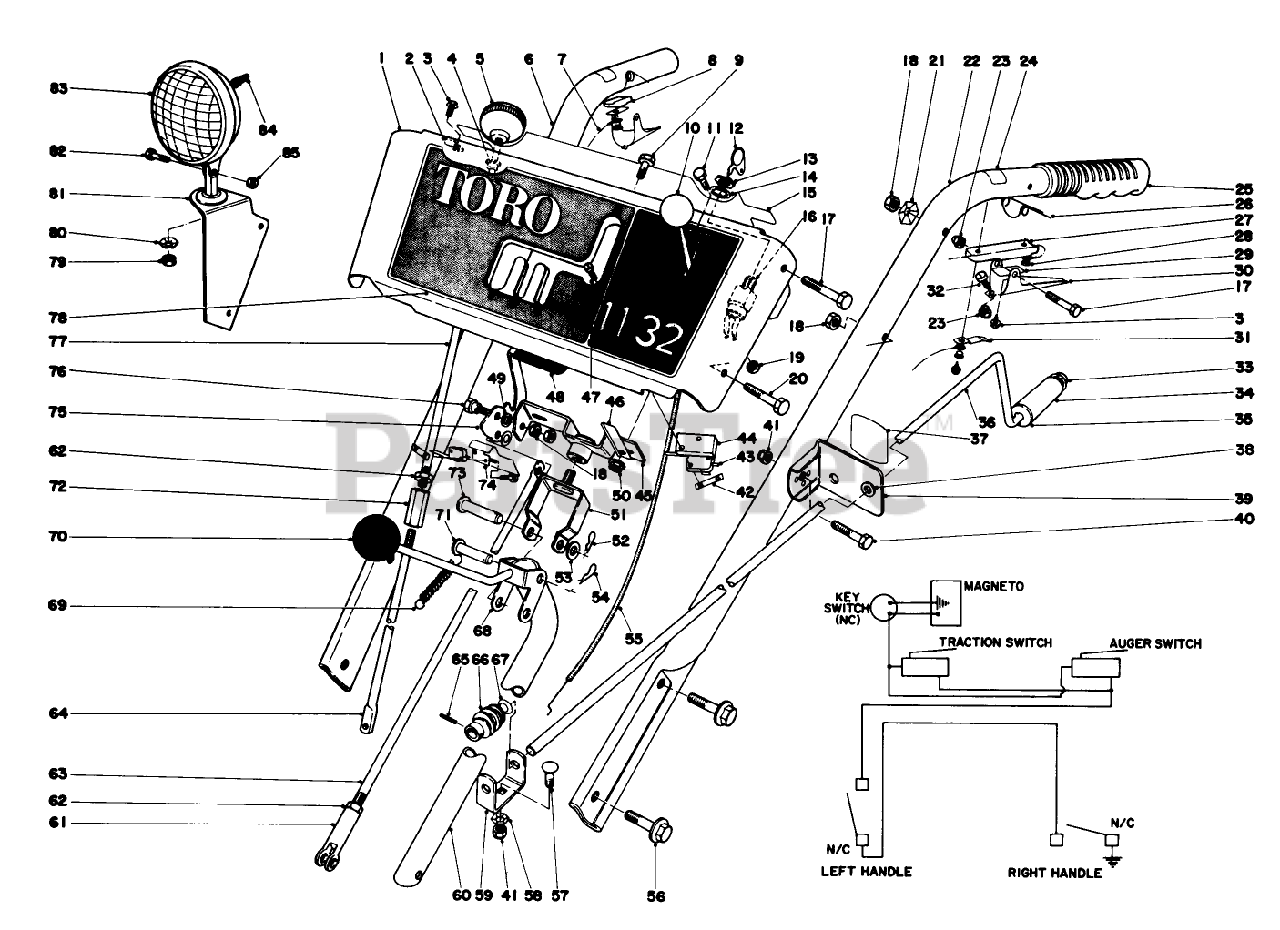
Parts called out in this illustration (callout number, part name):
4	NYLINER #6LI-FF TYPE 7
5	KNOB-LEVER
9	SCREW-HH
13	NUT-HH
14	WASHER-LOCK
16	SWITCH-ON / OFF
17	SCREW-HH
18	NUT-LOCK, CONE
20	SCREW-HH
22	LEFT HANDLE
23	NUT-CAP
27	DUAL BRKT INSULATOR
28	BUSHING-INSULATOR
29	INTERLOCK CONTACT
31	CONTACT BRACKET
32	NYLON SCREW 1/4 20
33	NUT-PUSH
35	WASHER-FLAT
40	SCREW-HH
41	NUT-LOCK, NI
42	NUT-SPEED
47	SCREW-SPH
49	WASHER-PLAIN
50	NUT-LOCK, HHF
52	PIN-HAIR
53	WASHER-FLAT
56	SCREW-HHF
57	BOLT-CARR
58	WASHER-LOCK
61	Clevis
62	NUT-HJ
64	LOWER WHL CLUTCH ROD
65	PIN-SPRING
66	GEAR-WORM, CHUTE
67	WASHER-SPRING
68	SHIFT ROD WA
71	PIN-CLEVIS
72	WHL ROD COUPLING
73	PIN-CLEVIS
74	SWITCH BRKT
76	SCREW-SHOULDER
79	NUT-HEX
80	LOCKWASHER-PYRAMID
82	SCREW-HH
84	BOOT-SWITCH
85	NUT-HEX, SIDE DEFORM
